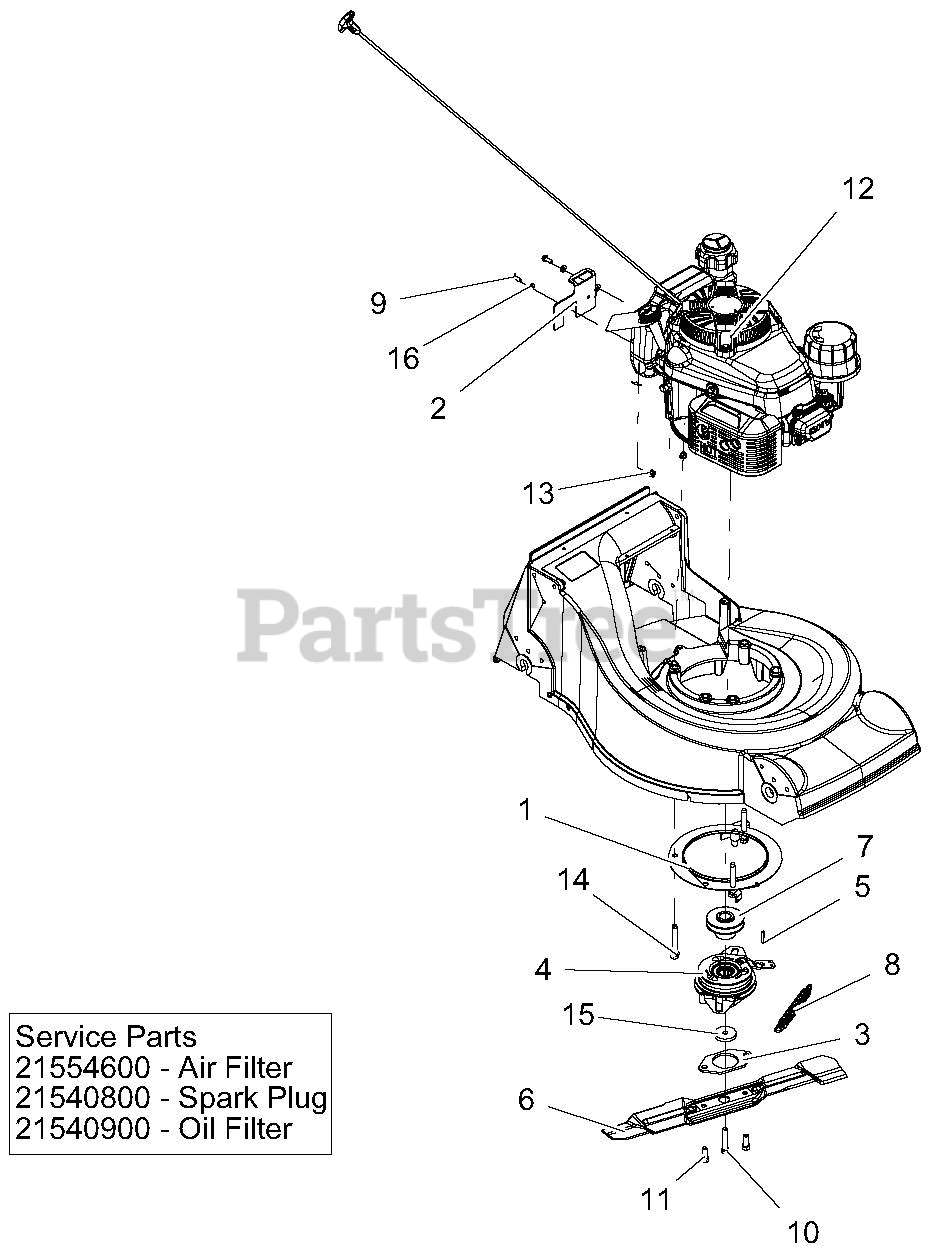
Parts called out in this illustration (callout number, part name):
1	WLDMT, PLATE -BBC
2	BRKT, FUEL TANK
3	SPCR, BBC BLADE
4	KAWASAKI, BBC
5	KEY 3/16 X 3/16 X 1
6	BLADE, MOWER 21" HIGH-LIFT
7	PULLEY, SP, KAWI, BBC
8	SPRG, EXTENSION BBC
9	BLT-HEX .25-20X.75 GR5 YWZC
10	BLT-HEX .38-24X2.00 YWZC GR8
11	BLT-HEX M10 X 1.5X20 GR5 YWZC
12	ENGINE, KAWASAKI BBC - 49ST
13	NUT, LK-TOP-FLG .25-20 YWZC
14	SCR-TAP.375-16X2.75 HWH TR YZ
15	WSHR-FL-STL .400X1.75X.250
16	WSHR-FL-STL.250X.562X.049YWZC
17	AIR FILTER
18	SPARK PLUG
19	OIL FILTER
